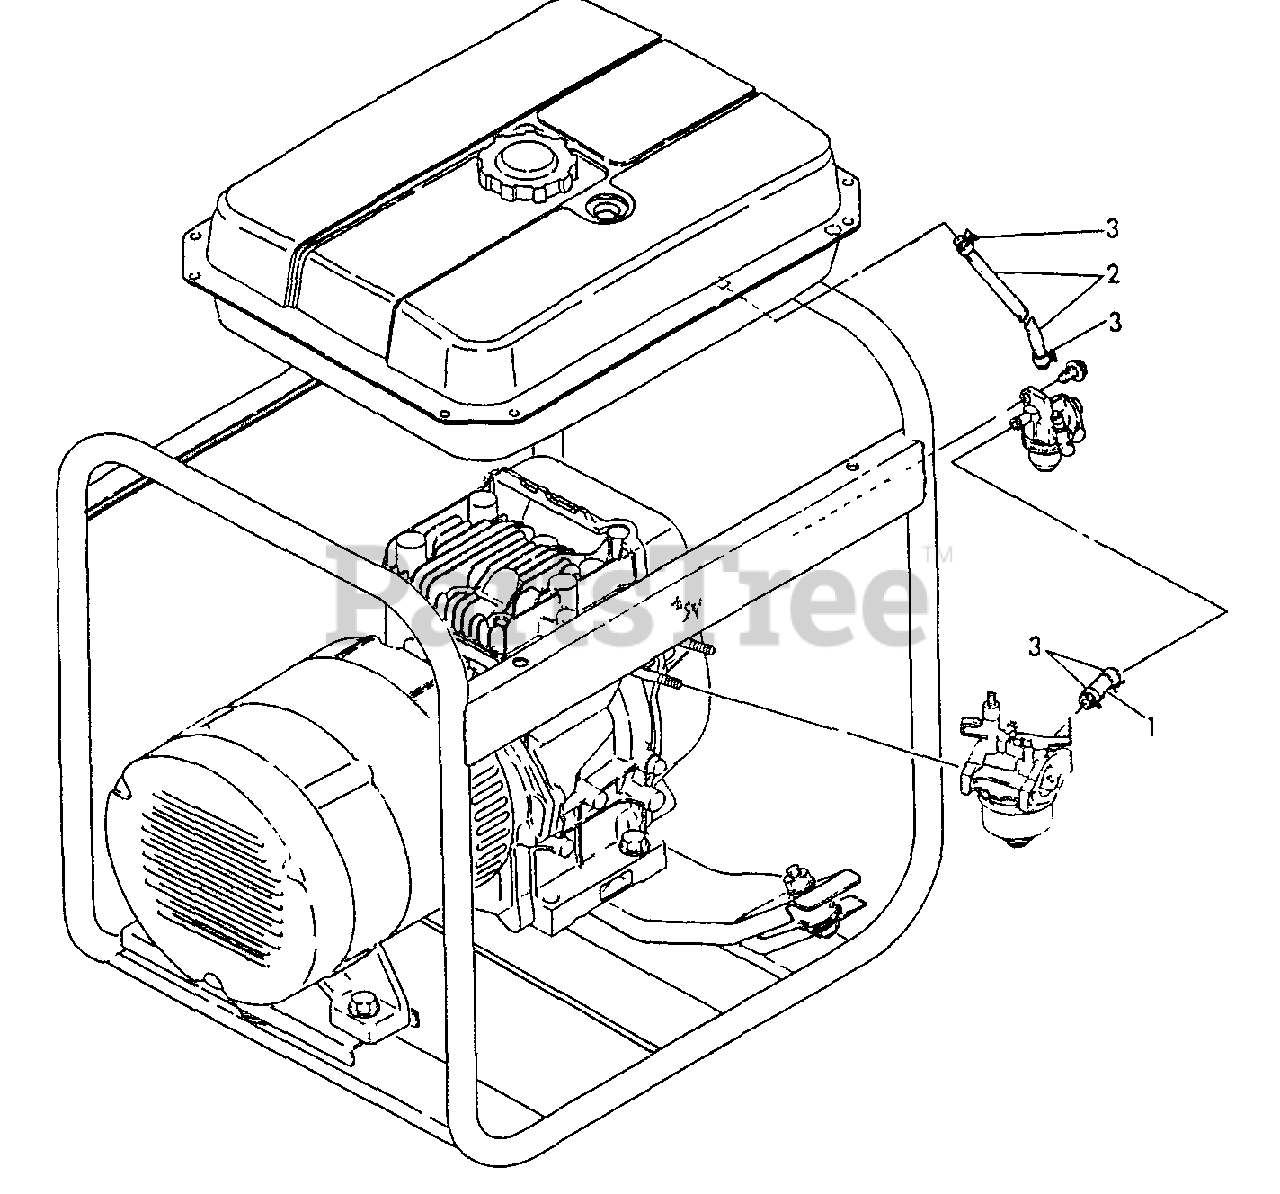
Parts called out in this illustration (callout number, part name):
1	PIPE - FUEL
2	PIPE - FUEL
3	CLAMP
